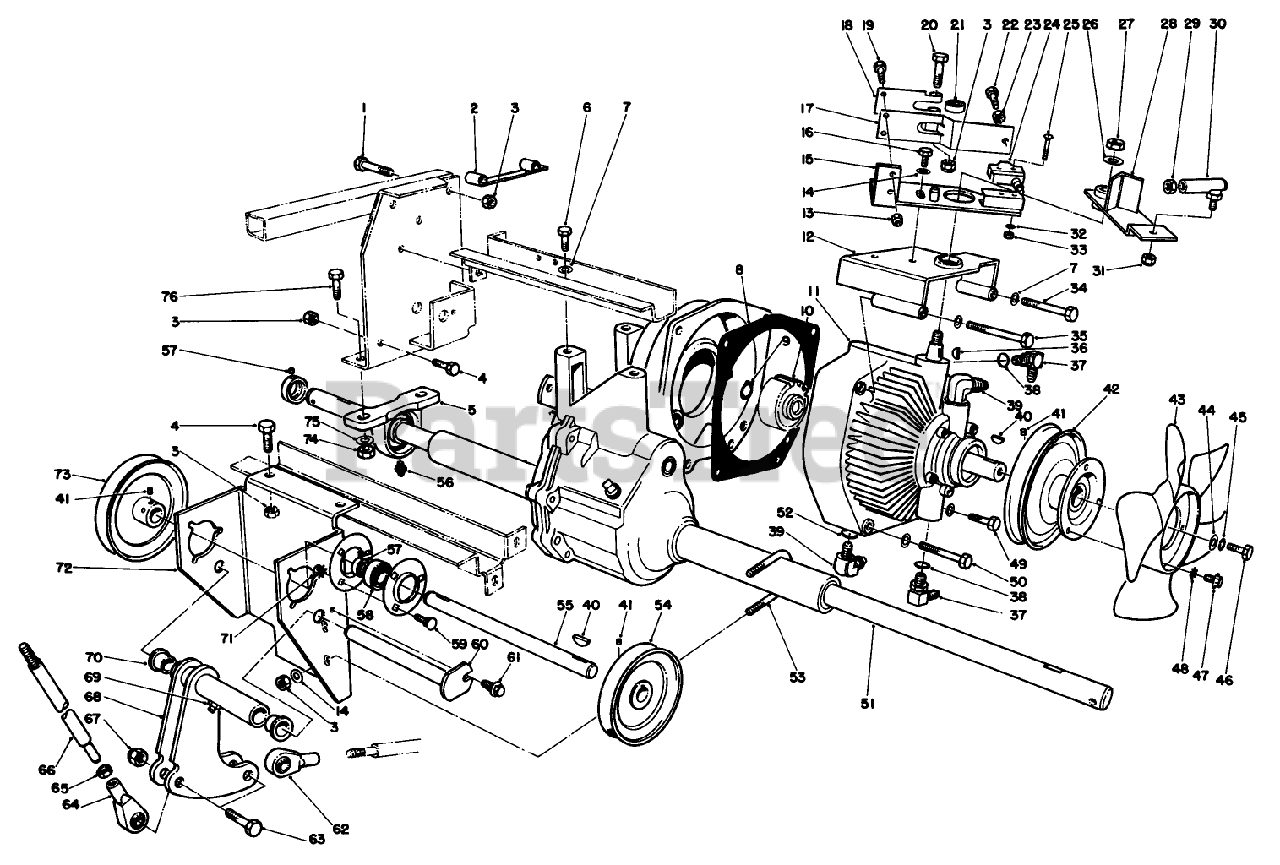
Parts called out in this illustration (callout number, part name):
1	SCREW-HH
3	NUT-LOCK, NI
4	SCREW-HH
6	SCREW-HH
7	SCREW-HH
9	RING-SNAP, EXTERNAL
10	GEAR-SPUR
11	HYDROSTATIC TRANS.
13	NUT-LOCK, NI
14	WASHER-PLAIN
16	SCREW-HH
17	EXTENDED LEAF SPRING ASM
19	SCREW-HH
20	SCREW-HH
21	BEARING-BALL
22	SCREW-HH
23	NUT-JAM
25	SCREW-MACHINE
26	WASHER-FLAT
27	NUT-HEX
29	NUT-JAM
30	JOINT-BALL
31	NUT-LOCK
32	WASHER-LOCK, INTERNAL
33	NUT-HEX
34	SCREW-HH
36	KEY-WOODRUFF
37	FITTING-HYD, 90 DEG
38	O-RING
40	KEY-WOODRUFF
41	SCREW-HH
42	TRANS PULLEY
44	WASHER-FLAT
45	SCREW-HH
46	SCREW-HH
47	SCREW-SHWH
48	WASHER-LOCK, EXT
49	SCREW-HH
50	SCREW-HH
52	O-RING
53	U-BOLT
54	JACKSHAFT INPUT PULLEY
55	JACKSHAFT V
56	FITTING-GREASE
57	SCREW-SET, HSH
59	BOLT-CARR
61	SCREW-HHFTF
62	BALL JOINT LH
63	SCREW-HH
64	BALL JOINT RH
65	NUT-JAM
67	NUT-HEX
68	BELL CRANK ASSY
69	GREASE FITTING
70	BEARING-FLANGE
71	NUT-KEPS
73	JACKSHAFT OUTPUT PULLEY
74	NUT-LOCK, NI
75	WASHER-FLAT
76	SCREW-HH
